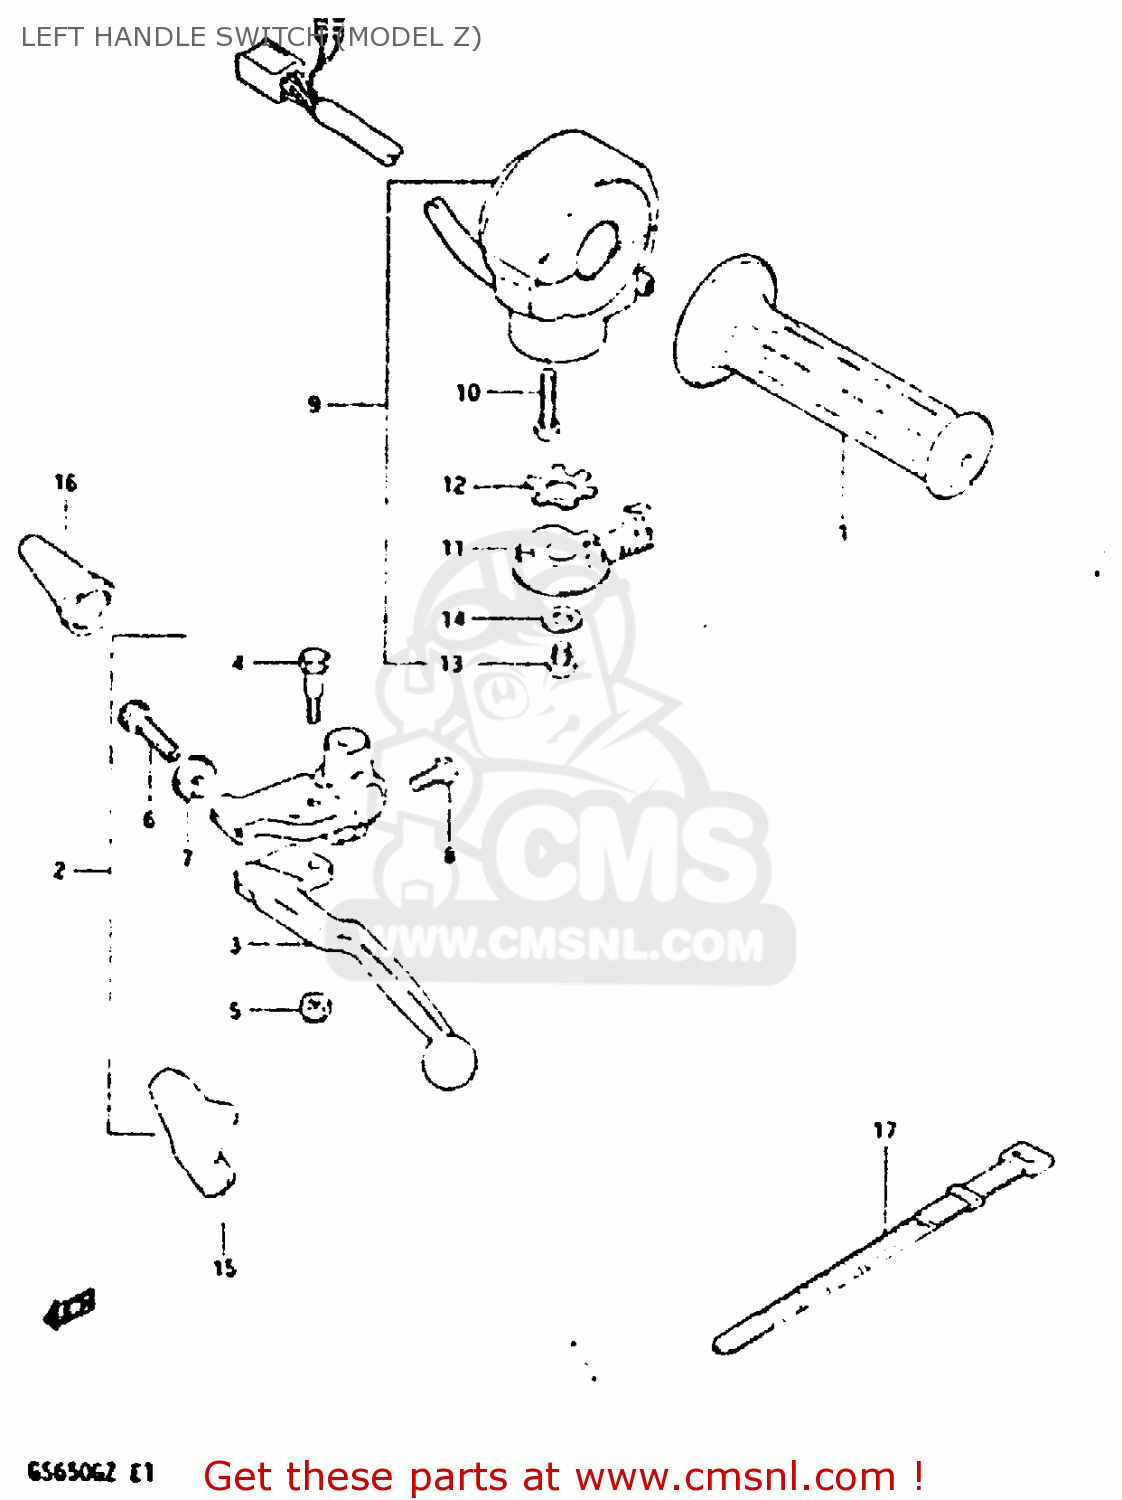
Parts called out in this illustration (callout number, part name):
1	GRIP,L
2	LEVER ASSEMBLY
3	LEVER,CLUTCH
4	BOLT,LEVER
5	NUT 6MM
6	ADJUSTER,CABLE
7	NUT,CABLE ADJUSTER
8	BOLT
9	SWITCH ASSY, HANDLE LH
10	SCREW
11	LEVER,STARTER
12	WASHER
13	SCREW
14	WASHER 6MM
15	COVER,CLUTCH LEVER
16	BOOT,CLUTCH CABLE
17	CLAMP(L:120)
